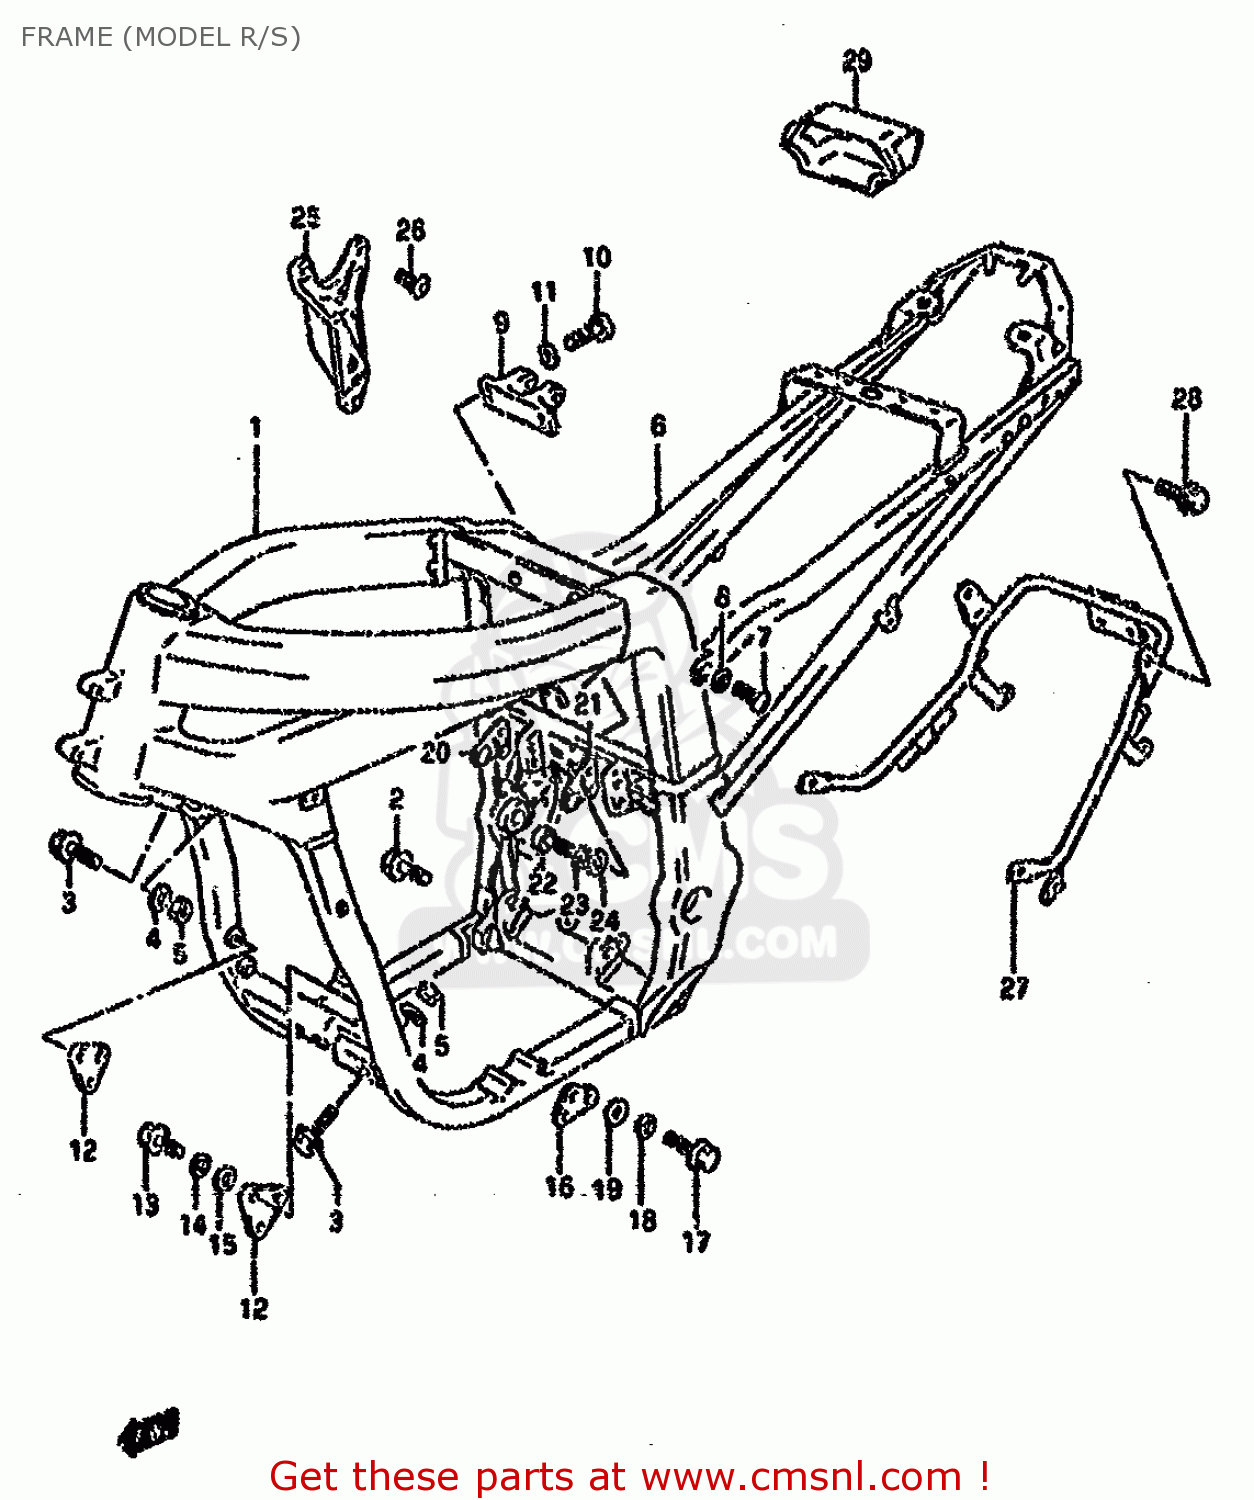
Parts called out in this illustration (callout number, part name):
1	FRAME SET
2	BOLT
3	BOLT
4	WASHER (10.1X21X2.3)
5	NUT
6	RAIL COMP,SEAT
7	BOLT,FOOTREST BRACKET
8	WASHER
9	BRACKET,R.C.U.
10	BOLT(8X28)
11	WASHER
12	PLATE,ENG MTG NO.1
13	BOLT
14	LOCK WASHER
15	WASHER (8.2X20X1.6)
16	PLATE,ENG MTG NO.2,R
17	BOLT
18	LOCK WASHER
19	WASHER (8.2X20X1.6)
20	PLATE,ENGINE MOUNTING NO.3
21	PLATE,ENG MTG NO.3,L
22	BOLT(8X22)
23	LOCK WASHER
24	WASHER (8.2X20X1.6)
25	PLATE,ENGINE MOUNT UPR
26	BOLT
27	GRIP,REAR
28	BOLT
29	HOLDER,TOOL
30	BAND
31	WASHER (6.5X20X1)
32	NUT
